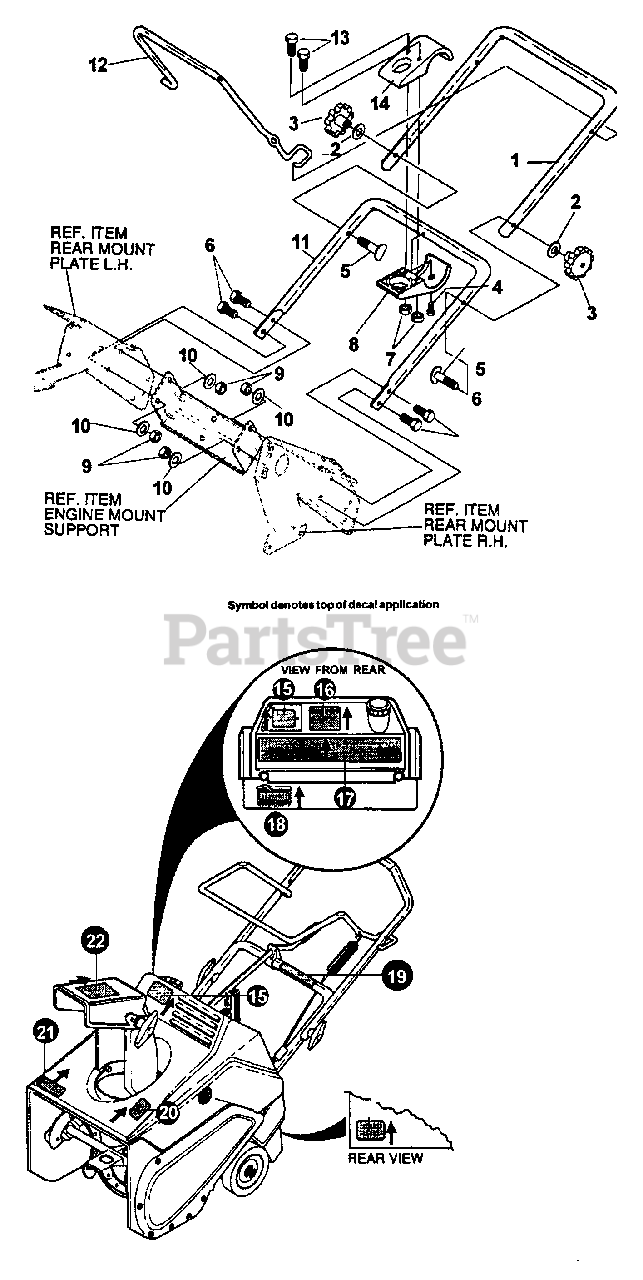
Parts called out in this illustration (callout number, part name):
1	HANDLE - UPPER
2	WASHER
3	KNOB KIT
4	SCREW - 1/4-20 X .63" -- TAPPING
5	BOLT, 5/16-18 X 2.00
6	SCREW - 5/16-18 X 3/4"
7	LOCKNUT - 10-24
8	BRKT HALF, CHUTE CRANK
9	NUT - 5/16-18
10	WASHER
11	HANDLE - LOWER
12	BAR, DRIVE CONTROL LOOP
13	SCREW - 10-24 X 1.00"
14	BRKT HALF, CHUTE CRANK
15	LABEL - ECHO -- ST-5000E
16	LABEL - STARTING
17	LABEL - CONTROL PANEL
18	LABEL - CHOKE
19	LABEL - AUGER CONTROL BAR
20	LABEL - DANGER
21	LABEL - ECHO
22	LABEL - DANGER
